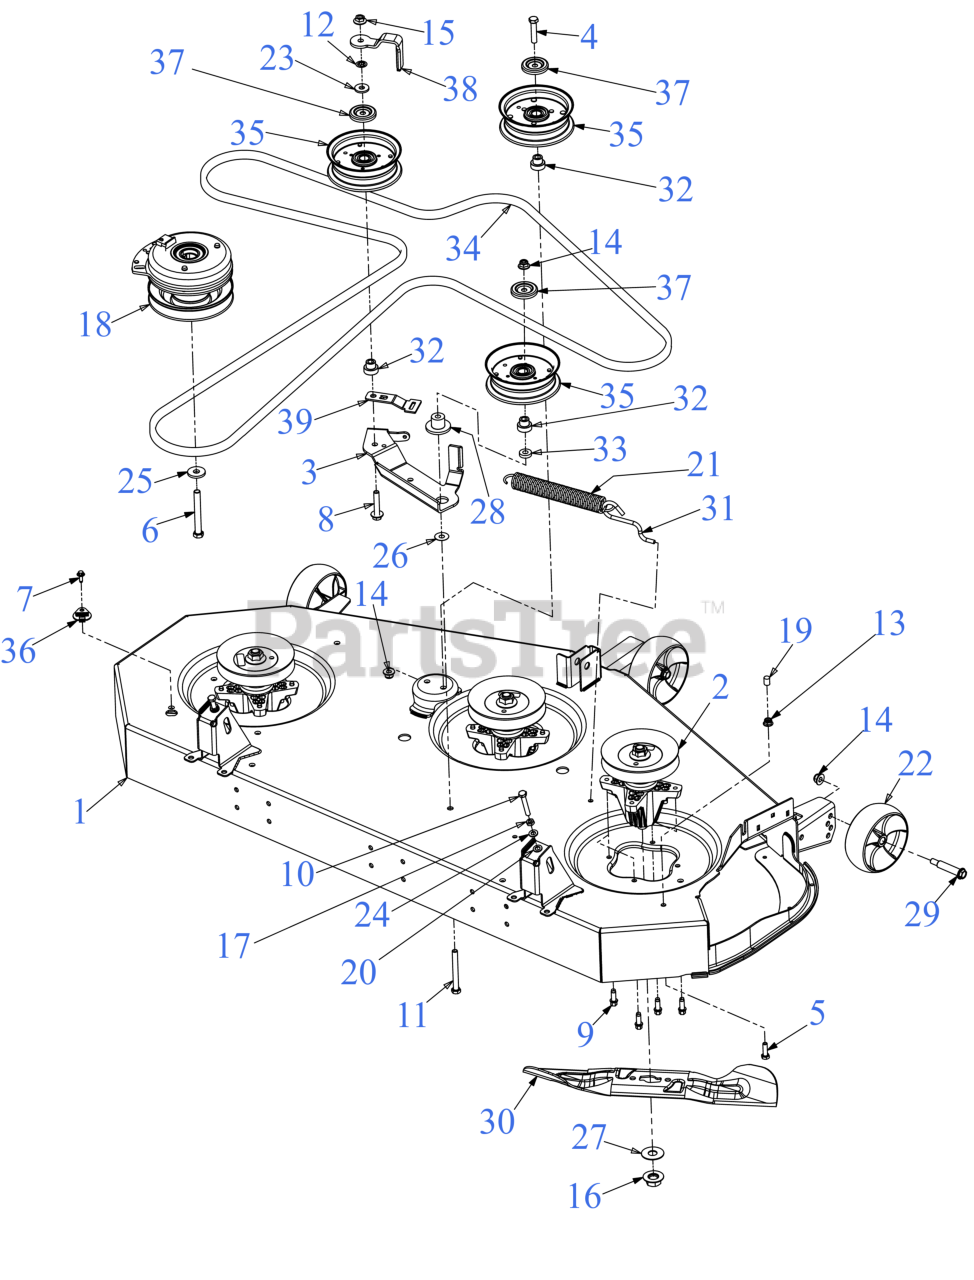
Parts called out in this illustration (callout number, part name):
1	54" FAB DECK SHELL
2	SPINDLE ASSEMBLY
3	DECK IDLER BRACKET
4	HEX SCREW 3/8-16 x 1.75 GR5
5	SCREW 5/16-18 x 1.0 GR5
6	SCREW 7/16-20 x 3.5 GR5
7	SCREW M6-1 x .625
8	SCREW 3/8-16 x 2.0
9	SCREW 5/16-18 x .875
10	SCREW-FULL THREAD 5/16-18 GR5
11	SCREW 3/8-16 x 3.25 GR8
13	FLANGE LOCK NUT 5/16-18
15	FLANGE LOCK NUT
16	FLANGE NUT 5/8-18
18	ELECTRIC PTO CLUTCH
21	EXTENSION SPRING
22	DECK WHEEL (5.0 DIA x 1.875)
22	Cub Cadet 5" DECK WHEEL (06305A) (W/BOLT)
23	FLAT WASHER .385 x 1.00 x .135
24	FLAT WASHER
25	FLAT WASHER .445 x 1.248 x .170
26	FLAT WASHER
27	FLAT WASHER .635X1.585X.062 HDN
28	NUT RIVET 5/16-18
28	SHOULDER SPACER
29	SHOULDER BOLT (.50 X 2.0 x 3/8 -16)
30	18.611" BLADE (2IN1) (S SHAPE CENTER HOLE)
30	Cub Cadet 54" HI LIFT BLADE SET (S SHAPE CENTER HOLE)
30	Troy-Bilt 54" HI LIFT BLADE SET (S SHAPE CENTER HOLE)
30	18.611" XTREME BLADE (2IN1) (S SHAPE CENTER HOLE)
30	Cub Cadet 54" XTREME BLADE SET (S SHAPE CENTER HOLE)
30	Troy-Bilt 54" XTREME BLADE SET (S SHAPE CENTER HOLE)
30	18.611" LOW LIFT (S SHAPE CENTER HOLE)
30	Cub Cadet 54" LOW LIFT BLADE SET (S SHAPE CENTER HOLE)
30	Troy-Bilt 54" LOW LIFT BLADE SET (S SHAPE CENTER HOLE)
31	DECK SPRING HOOK
32	SHOULDER SPACER
34	V-BELT B SEC x 148.25
34	Cub Cadet 54" DECK DRIVE BELT
34	Troy-Bilt 54" DECK DRIVE BELT
35	IDLER PULLEY 4.50" DIA
36	DECK WASH PLUG
37	IDLER PULLEY CAP
38	BELT KEEPER
